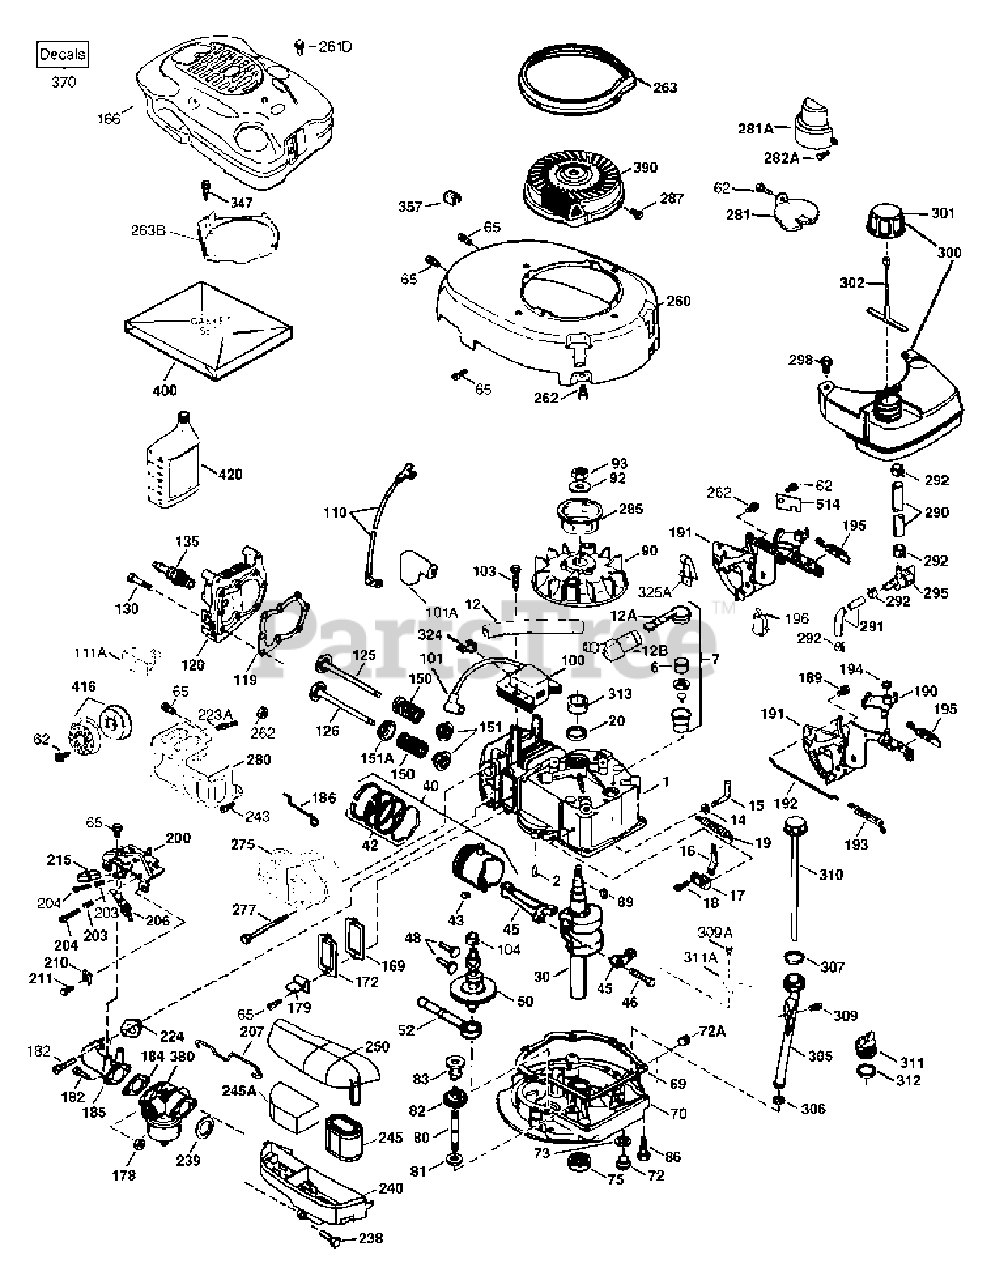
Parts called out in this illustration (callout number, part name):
1	Cylinder (Incl. 2 & 29)
2	Dowel Pin
6	Breather Element
7	Breather Ass'y. (Incl. 6 & 12A)
12	Breather Tube
12A	Breather Cover & Tube
12B	Breather Tube Elbow
14	Flat washer
15	Governor Rod (Incl. 14)
16	Governor Lever
17	Governor Lever Clamp
18	Screw, T-15, 8-32 x 19/64"
19	Extension Spring
30	Crankshaft
40	Piston, Pin & Ring Set (Std.)(Incl. Ref.42)
40	Piston, Pin & Ring Set (.010" OS) (Incl. Ref. 42)
42	Ring Set (Std.)
42	Ring Set (.010" OS)
43	Piston Pin Retaining Ring
45	Connecting Rod Ass'y.(Incl. 46)
46	Connecting Rod Bolt
48	Valve Lifter
50	Camshaft (Exhaust MCR) (Incl. Ref 104)
52	Oil Pump Ass'y.
65	Screw, 10-24 x 9/16"
69	Flange Gasket (With Silicon Bead)
70	Mounting Flange (Incl. 72 thru 83, 306, 309A & 311A)
72	Oil Drain Plug (Flush Mount)
72A	Oil Drain Plug
80	Governor Shaft
81	Flat washer
82	Governor Gear Assembly (Incl 81)
86	Screw, 1/4-20 x 1-1/4"
89	Flywheel Key
92	Belleville Washer
93	Flywheel Nut
100	Solid State Ignition
101	Spark Plug Cover
103	Screw, T-15, 10-24 x 15/16"
104	Cam Bushing
110	Ground Wire (6.75")
119	Cylinder Head Gasket
120	Cylinder Head
125	Exhaust Valve (Std.) (Incl. 151)
126	Intake Valve (Std.) (Incl. 151)
130	Screw, 5/16-18 x 1-7/16"
130B	Screw, 1/4-20 x 1/2"
135	Resistor Spark Plug (RJ19LM)
150	Valve Spring
151	Valve Spring Cap
151A	Intake Valve Seal
166	Engine Shroud (Beige)
169	Valve Cover Gasket
172	Valve Cover
178	Nut & Lock Washer 1/4-28
179	Retaining Clip
182	Screw, 1/4-28 x 7/8"
184	Carburetor To Intake Pipe Gasket
185	Intake Pipe
186	Governor Link
200	Control Bracket(Incl. 203, 204, n& 206)
203	Compression Spring
204	Screw, T-10, 5-40 x 7/16"
207	Throttle Link
215	Control Knob
223A	Intake Pipe Stud
224	Intake Pipe Gasket 238
238	Screw, 10-32 x 49/64"
239	Air Cleaner Gasket
243	Screw, 10-32 x 7/16"
260	Blower Housing
261D	Screw T-20, 10-16 x 15/32"
262	Screw, 1/4-20 x 1/2"
263B	Shroud Mtg Ring
277	Screw, 1/4-20 x 2-9/32"
280	Heat Shield
285	Starter Cup
287	Screw, 8-32 x 21/64"
290	Fuel Line (16.0" length)
292	Fuel Line Clamp
300	Fuel Tank (Natural Incl. 292 & 301)
301	Fuel Cap (Black)(1-1/2" I.D.)
305	Oil Fill Tube
309A	Screw, 10-24 x 3/4"
311A	Hold Down Bracket
347	Screw, 10-32 x 27/32"
355	Starter Handle (standard)
370	Caution Decal
370	Speed Control Decal
370	Warning Decal
370	Decal - Primer 3X with Hand
380	Carburetor (Incl. 184)
390	Rewind Starter
400	Gasket Set (Incl. Items marked*)
420	SAE 30 4-Cycle Engine Oil (Quart) (Summer)
999	Summer Maintenance Kit
